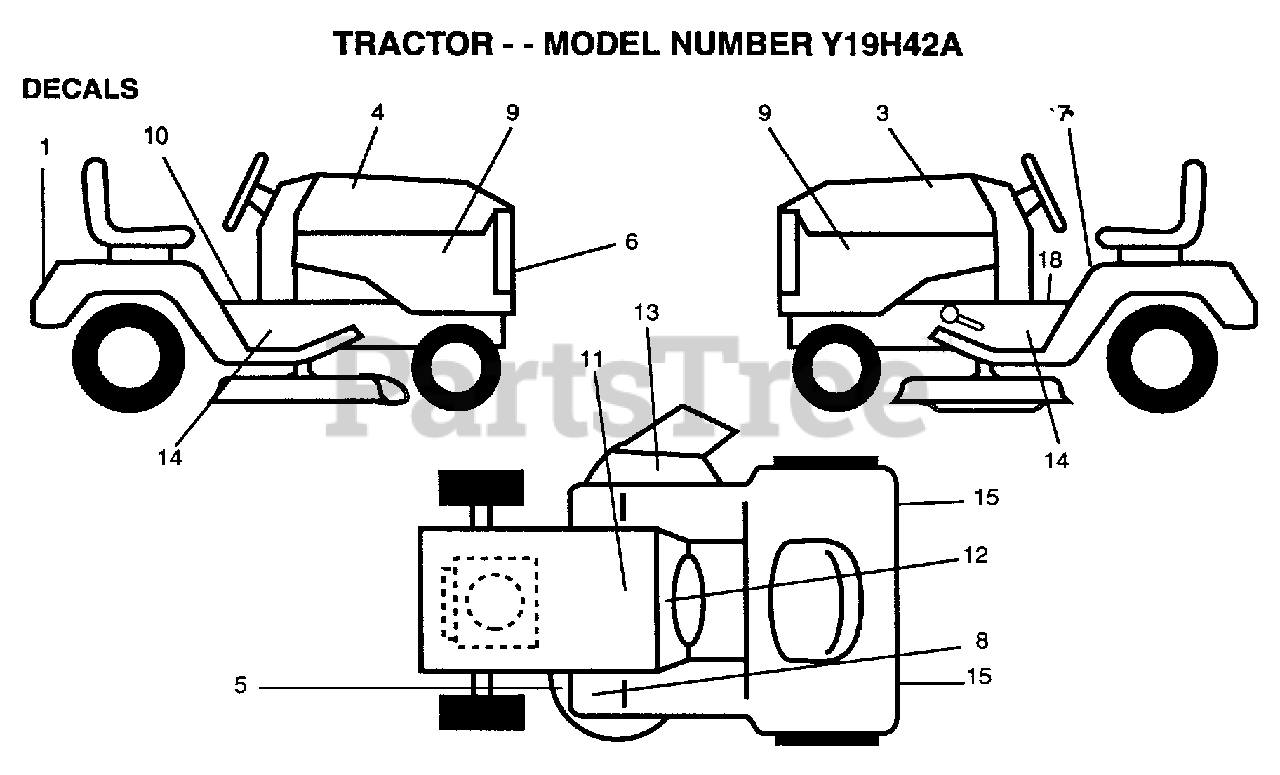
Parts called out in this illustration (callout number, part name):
3	DECAL HOOD LH
5	DECAL
6	DECAL.GRILL.YARDP
7	DECAL CAUTION
9	DECAL.PNL.SD.YP.
10	DECAL BRAK PARK
12	DECAL.DASH.INSTR.
13	"DECAL, WARNING"
14	DECAL CHAS 42 HYD
18	DECAL SADL HYDRO
